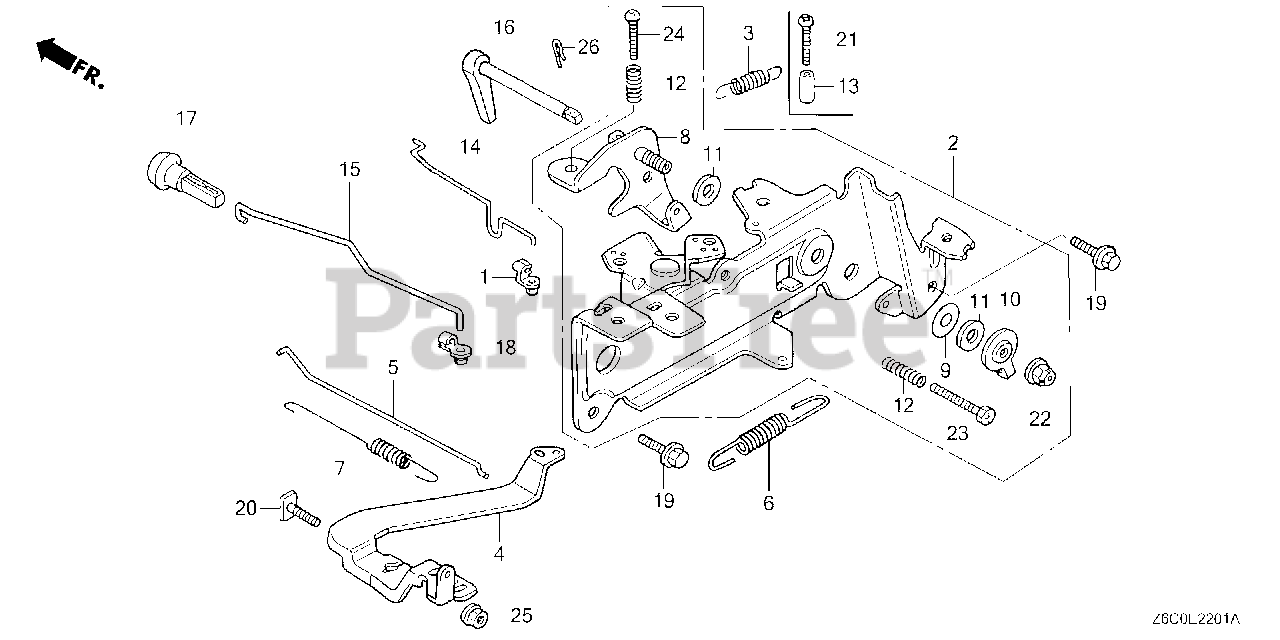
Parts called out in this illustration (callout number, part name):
1	JOINT, ROD
2	CONTROL ASSY.
3	SPRING, STARTER
4	ARM, GOVERNOR
5	ROD, GOVERNOR
6	SPRING, GOVERNOR (MANUAL)
7	SPRING, THROTTLE RETURN
8	ARM, CONTROL
9	SPRING, LEVER Use from Engine SN 2327377.
10	WASHER, CONTROL ARM
11	SPACER, CONTROL LEVER Use from Engine SN 2327377.
12	SPRING, CONTROL ADJUSTING Use from Engine SN 2327377.
13	COLLAR, STOPPER
14	ROD, CHOKE CONTROL
15	ROD, CHOKE KNOB
16	LEVER ASSY., THROTTLE
17	KNOB, CHOKE
18	BUSH, LINKAGE
19	BOLT, FLANGE (6X14)
20	BOLT, GOVERNOR ARM
21	SCREW, RECESSED (5X25)
22	NUT, SELF-LOCK (6MM)
23	BOLT, SLOT (5X25)
24	SCREW, PAN (5X25)
25	NUT, FLANGE (6MM)
26	PIN, LOCK (10MM)
